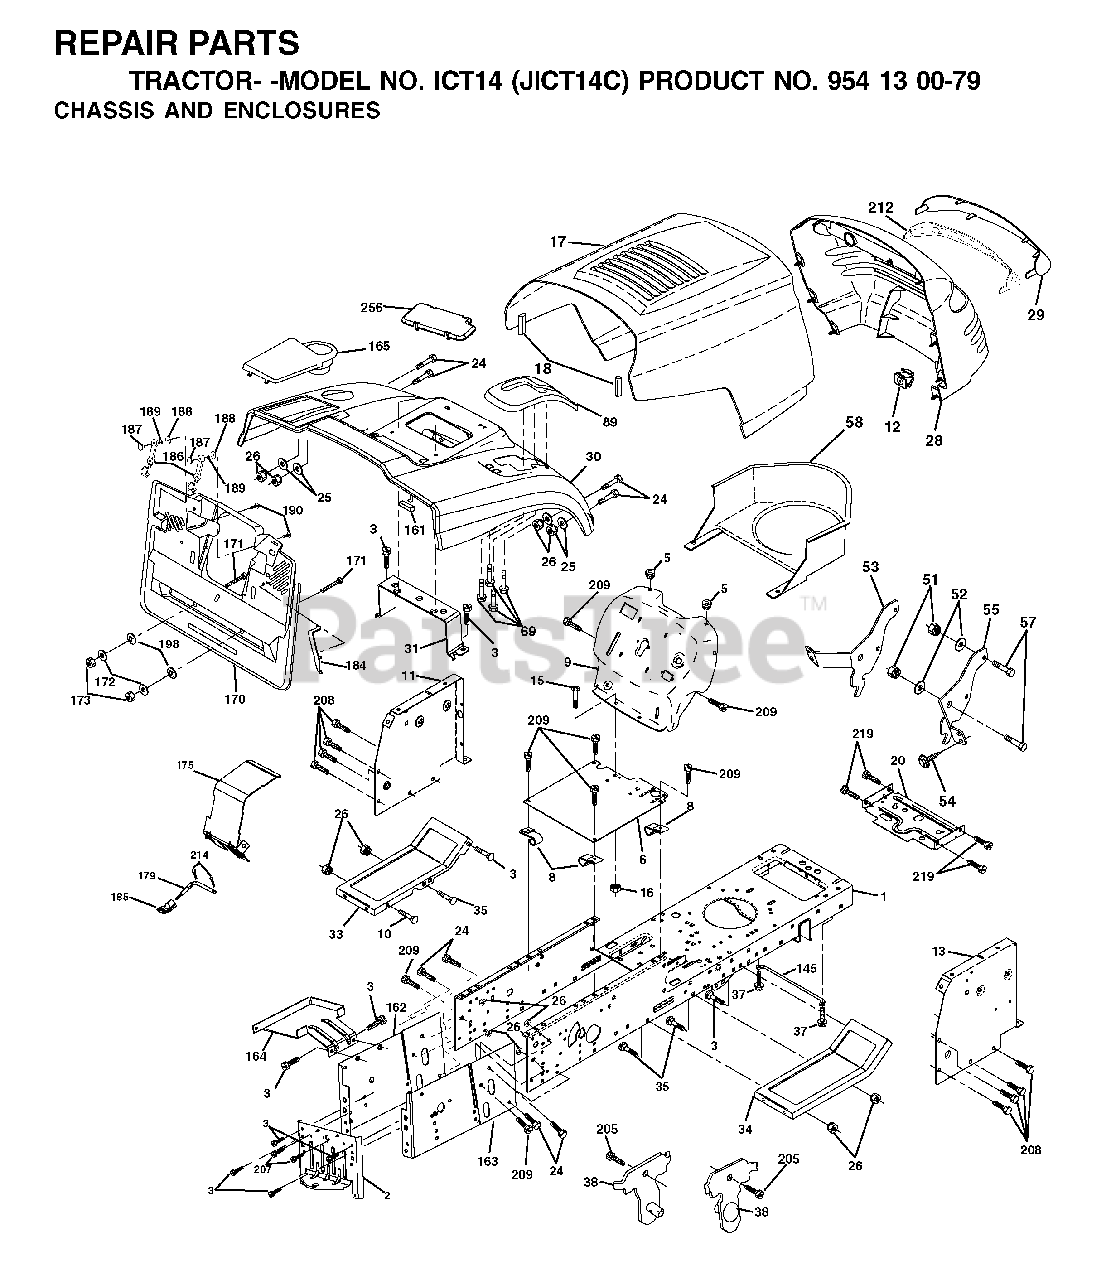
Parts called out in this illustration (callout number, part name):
1	CHASSIS
3	SCREW 3/8-16X3/4
5	BUMPER.RUBBER.HOOD
6	SADDLE FLAT
8	CLIP,INSULATOR
10	BOLT D
11	PANEL.DASH.LH.LTX
13	PANEL ASM, DASH RH
16	NUT
18	BUMPER HOOD T
20	PLATE MTG.BATTERY/FUEL TANK
25	WASHER
26	NUT
31	BRACKET SUPPORT FENDER
51	LOCKNUT
57	BOLT
69	SCREW.HI-LO.CONSOLE
145	ROD PIVOT CHASSIS/HOOD
161	EXTRUSION BUMPER
164	SUPPORT
171	BOLT
172	WASHER
186	LATCH ASSY
187	WELDNUT
189	LOCKWASHER
207	SCREW, 5/16-18 X 1/2
208	SCREW 3/8-16X1/2
209	SCREW, 3/8-16X3/4
214	RETAINER M
219	SCREW
